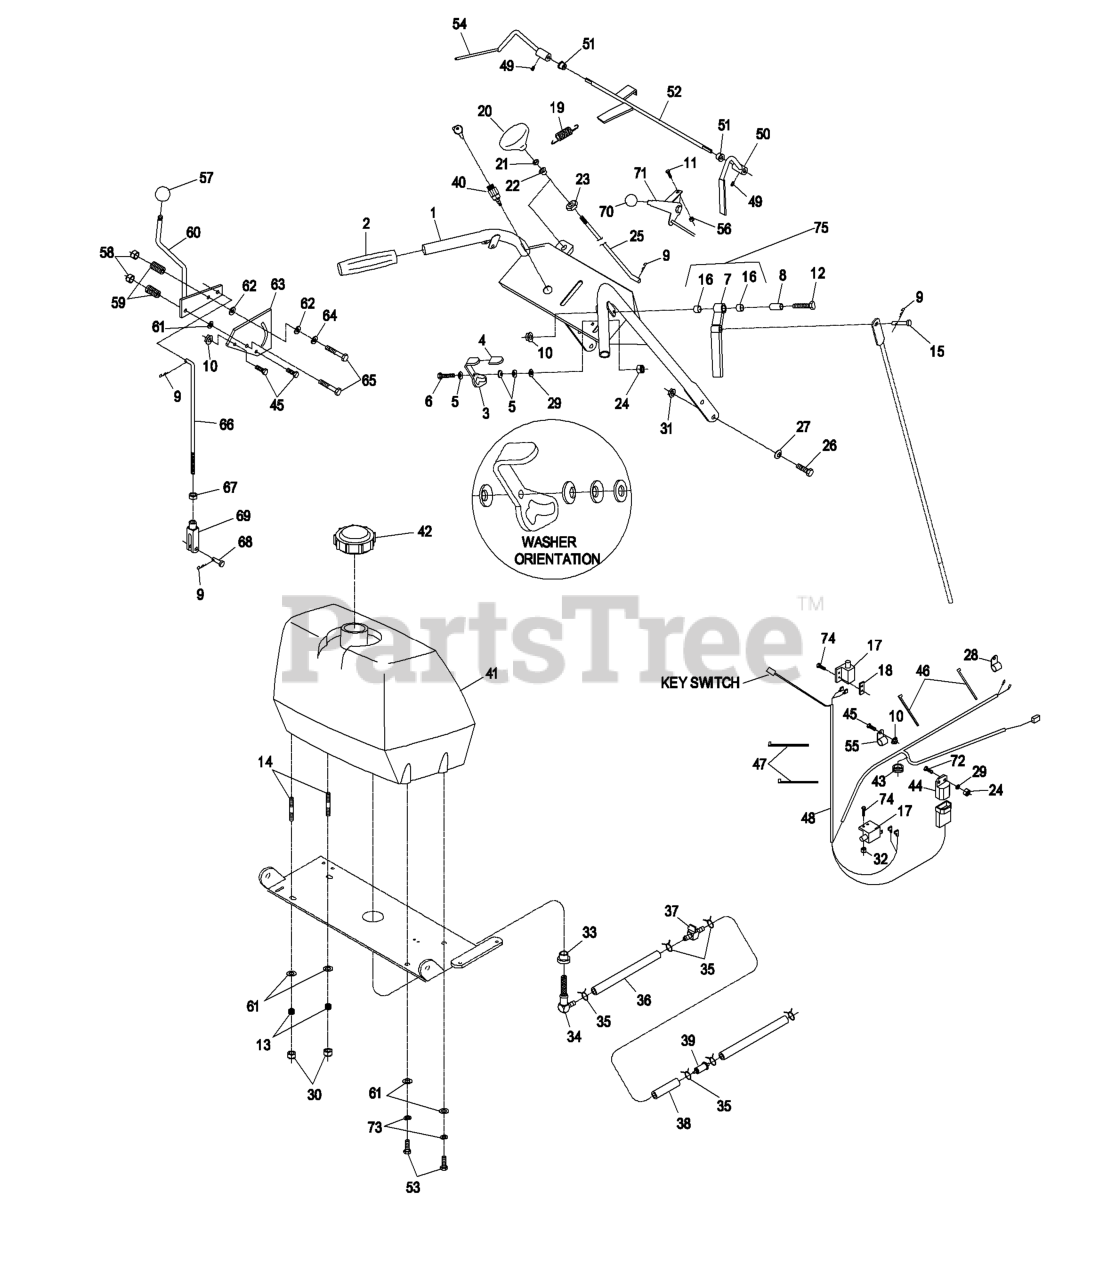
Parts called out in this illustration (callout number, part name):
1	KIT,HANDLE/DECALS VH
4	GRIP-LATCH
5	WASHER-SPRING
6	SCREW-HH
8	BUSHING-LEVER, DRIVE
9	PIN-COTTER
11	BOLT-CARR
12	SCREW-HH
13	SPRING-TANK, FUEL
14	STUD
15	PIN-CLEVIS
16	BUSHING-SLEEVE
17	SWITCH-OPEN, NORMALLY
18	PLATE-TAPPED
19	SPRING-EXTENSION
20	KNOB-PUSH / PULL
21	NUT-JAM
22	BEARING-NYLON
23	NUT-PUSH
24	NUT-LOCK, NI
25	LINKAGE-BLADE
26	SCREW-HH
27	WASHER-BELLEVILLE
28	CLIP-LOOM
29	WASHER-FLAT
30	NUT-LOCK, NI
31	NUT-HHF, WHIZ
32	NUT-SQH
34	ELBOW-TANK, FUEL
36	HOSE-FUEL
37	VALVE-FUEL
38	HOSE-FUEL
39	Fuel Filter
40	SWITCH & KEY (INCLUDES NU
42	CAP-FUEL
43	GROMMET
44	MODULE-INTERLOCK
45	SCREW-HH
46	TIE-CABLE
47	TIE-PLASTIC
48	HARNESS-WIRING
49	SCREW-SET
50	LEVER-RH
51	BUSHING-NYLON
52	WLD,ROD OPC
53	SCREW-HH
54	LEVER-LH
55	CLIP-LOOM
56	NUT-LOCK, NI
57	KNOB-BALL
58	NUT-LOCK, NI
59	SPRING-COMPRESSION
61	WASHER-PLAIN
62	WASHER-FRICTION
63	PLATE-LEVER, SHIFTER
64	WASHER-FRICTION
65	SCREW-HH
66	ROD-CONTROL, SPEED
67	NUT-JAM
68	PIN-CLEVIS
69	YOKE-ADJUSTABLE
70	KNOB-BALL
71	CONTROL,THROTTLE
72	SCREW-HH
73	WASHER-LOCK
74	SCREW-PPH
75	RH DRIVE LEVER ASM
